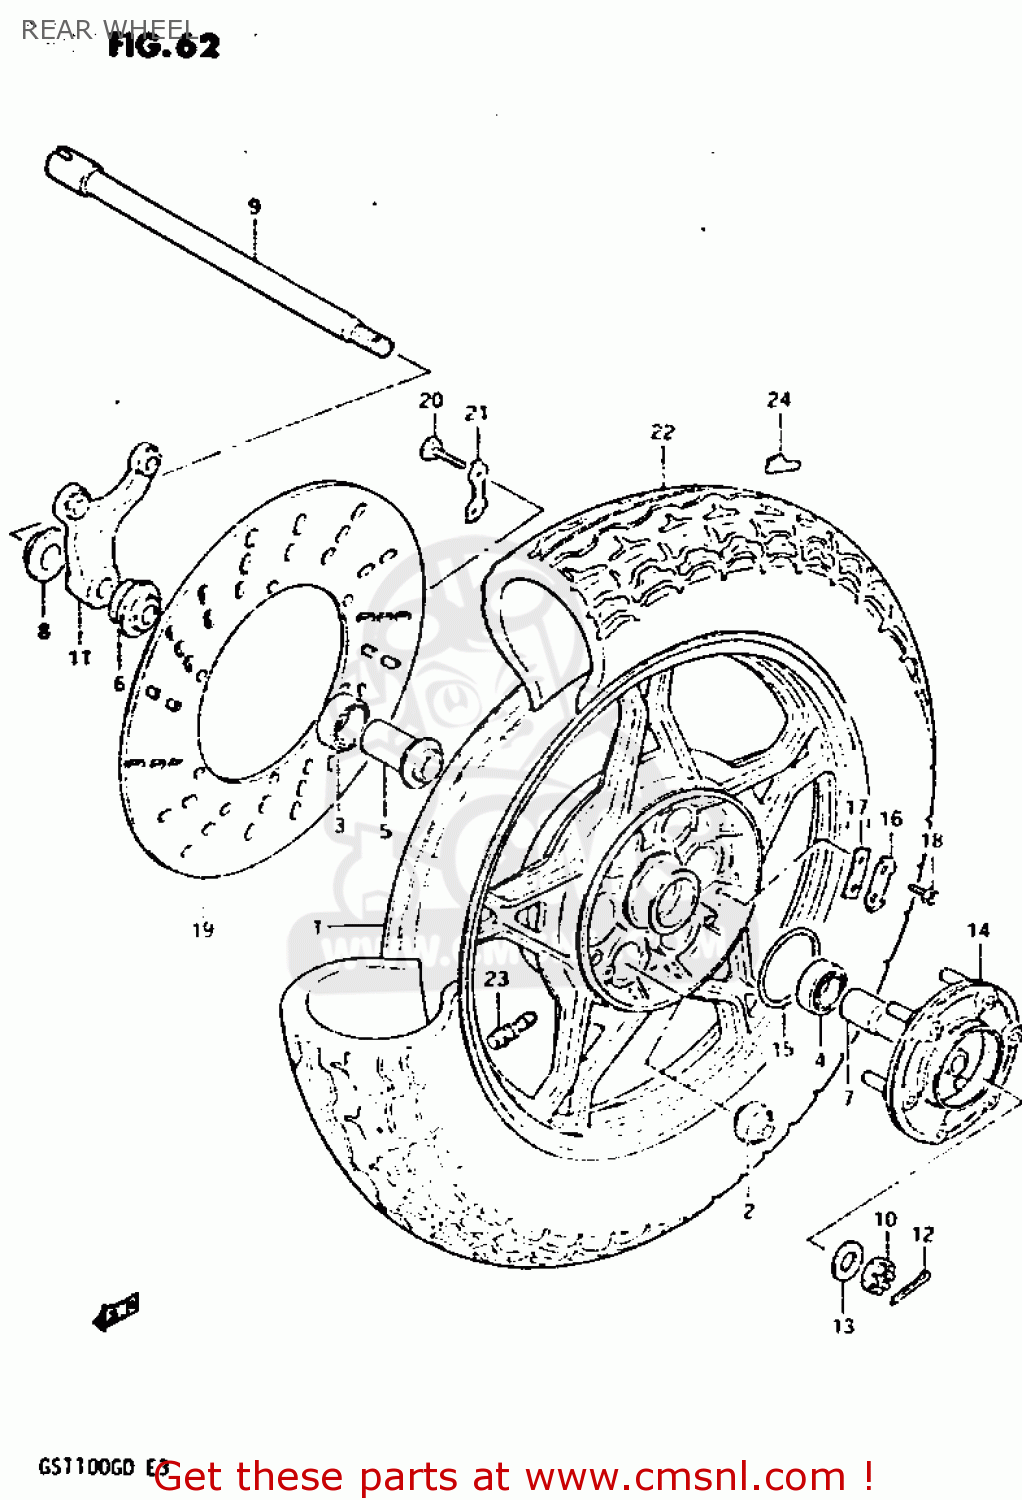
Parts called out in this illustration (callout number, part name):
1	CASTING WHEEL,REAR 2.50
2	BUSH
3	BEARING
4	BEARING
5	SPACER,REAR HUB BEARING
6	SPACER,REAR CALIPER BRACKET
7	SPACER,REAR AXLE,LEFT
8	SPACER,REAR AXLE,RIGHT
9	AXLE,REAR
10	NUT
11	BRACKET,RR,CALIPER
12	PIN,COTTER
13	WASHER (17.5X36X3.2)
14	JOINT ASSY,RR HUB DRIVEN
15	O RING(D:2.1,ID:65)
16	WASHER
17	WASHER,THRUST(T:1.6)
18	SCREW
19	DISC,RR BRAKE
20	BOLT(8X25)
21	WASHER
22	TIRE
23	VALVE ASSEMBLY,WHEEL RIM,J
24	BALANCER,WHEEL
